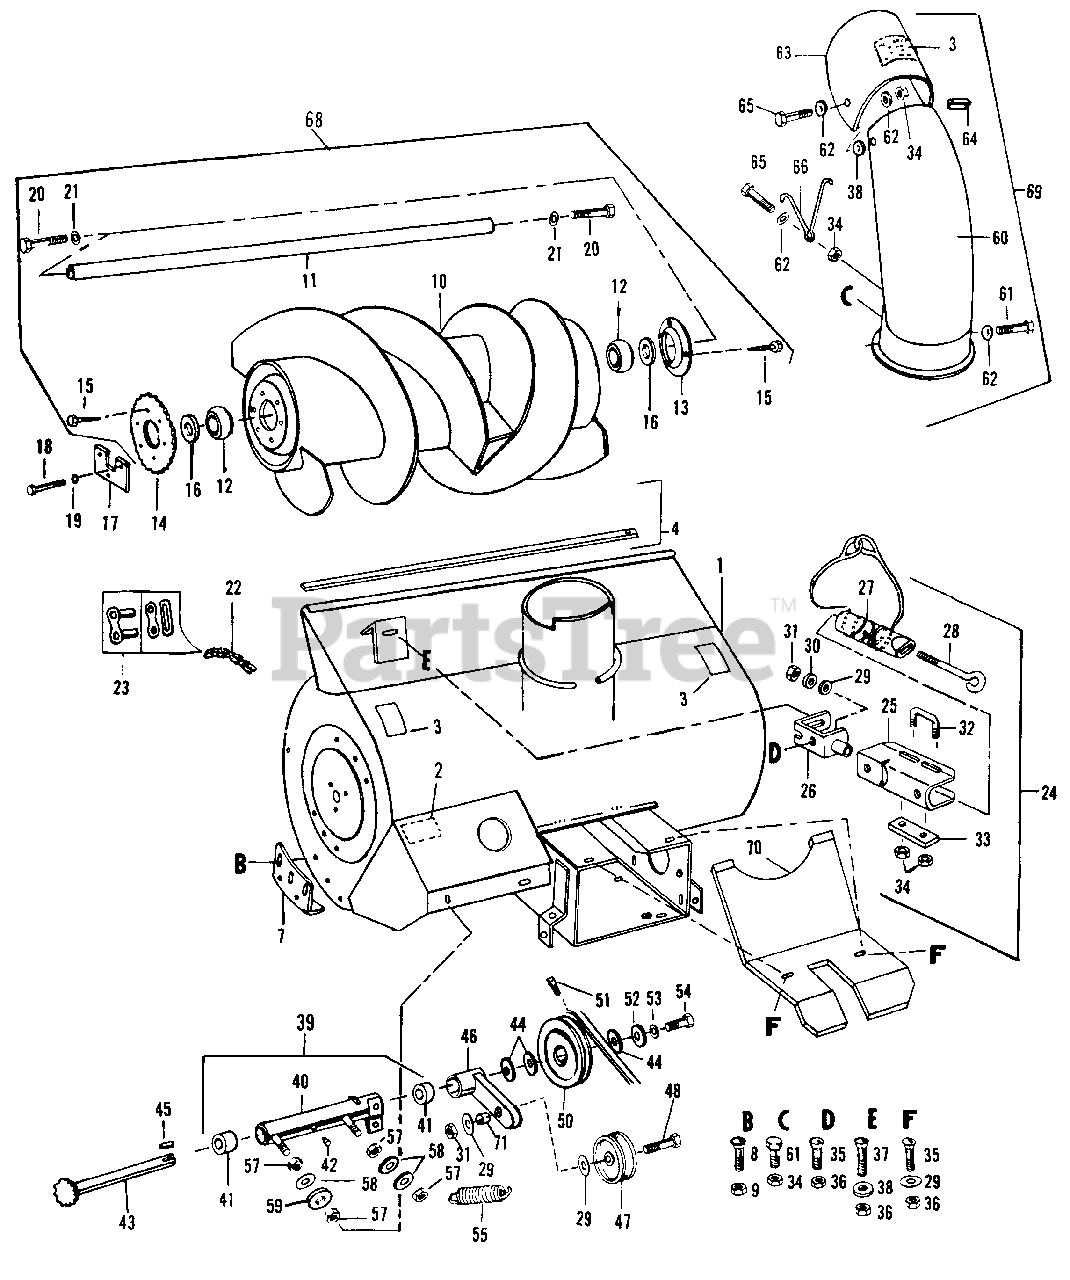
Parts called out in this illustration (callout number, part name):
1	Header & Decal Assembly
2	Caution Decal
3	Warning Decal
4	Scraper Blade Repair Kit
7	Skid Shoe
9	Nut & Lock Washer Assembly-5/16-18 Hex
10	Auger Assembly
11	Auger Shaft
12	Auger Shaft Bearing
13	Bearing Flange
14	Auger Sprocket (35 Tooth)
15	Self Tapping Screw
17	Auger Mounting Plate
18	Bolt - 5/16-18 x 5/8" Hex Head
19	Washer - 5/16" Medium Lock
20	Bolt -1/2-13 x 1 1/4" Hex Head
21	Washer - 1/2" Medium Lock
22	Auger Drive Chain (70 Links)
23	Repair Kit For Chain
24	Stack Drive Bracket Assembly
25	Stack Drive Shroud
26	Bracket & Tube Assembly
27	Cable, Tube & Sleeve Assembly
29	Washer - 7/16" x 1" x .083 Flat
30	Spring Washer
31	Nut - 3/8-16 Hex Lock
33	Friction Strap
35	Bolt - 3/8-16 x 3/4" Carriage
36	Nut & Lock Washer Assembly - 3/8-16 Hex
37	Bolt - 3/8-16 x 1" Carriage
39	Jackshaft Housing & Bushing Assembly
40	Jackshaft Housing Assembly
42	Grease Fitting
43	Jackshaft & Sprocket Assembly
44	Washer - 13/16" x 1 1/2" x .134 Flat
46	Idler Arm Assembly
47	Idler Pulley Assembly
48	Bolt - 3/8-16 x 2 1/2" Hex Head
50	Pulley & Hub Assembly
51	Screw - 5/16-18 x 1/2" Square Head Cup Point Set
52	Washer - -3/8" x 7/8" x .083 Flat
53	Washer - 3/8" Medium Lock
54	Bolt - 3/8-16 x 3/4" Hex Head
57	Nut - 1/2-13 Hex
58	Washer - 1/2" x 1 1/4" x .083 Flat
60	Deflector & Elbow Assembly
61	Bolt - 1/4-20 x 1/2" Hex Head
62	Cable Washer
63	Decal & Deflector Assembly
64	Deflector Molding
65	Bolt -1/4-20 x 3/4" Hex Head
66	Lift Spring Hook
68	Auger Assembly (Complete)
69	Deflector & Elbow Assembly (Complete)
70	Drive Pulley Guard
